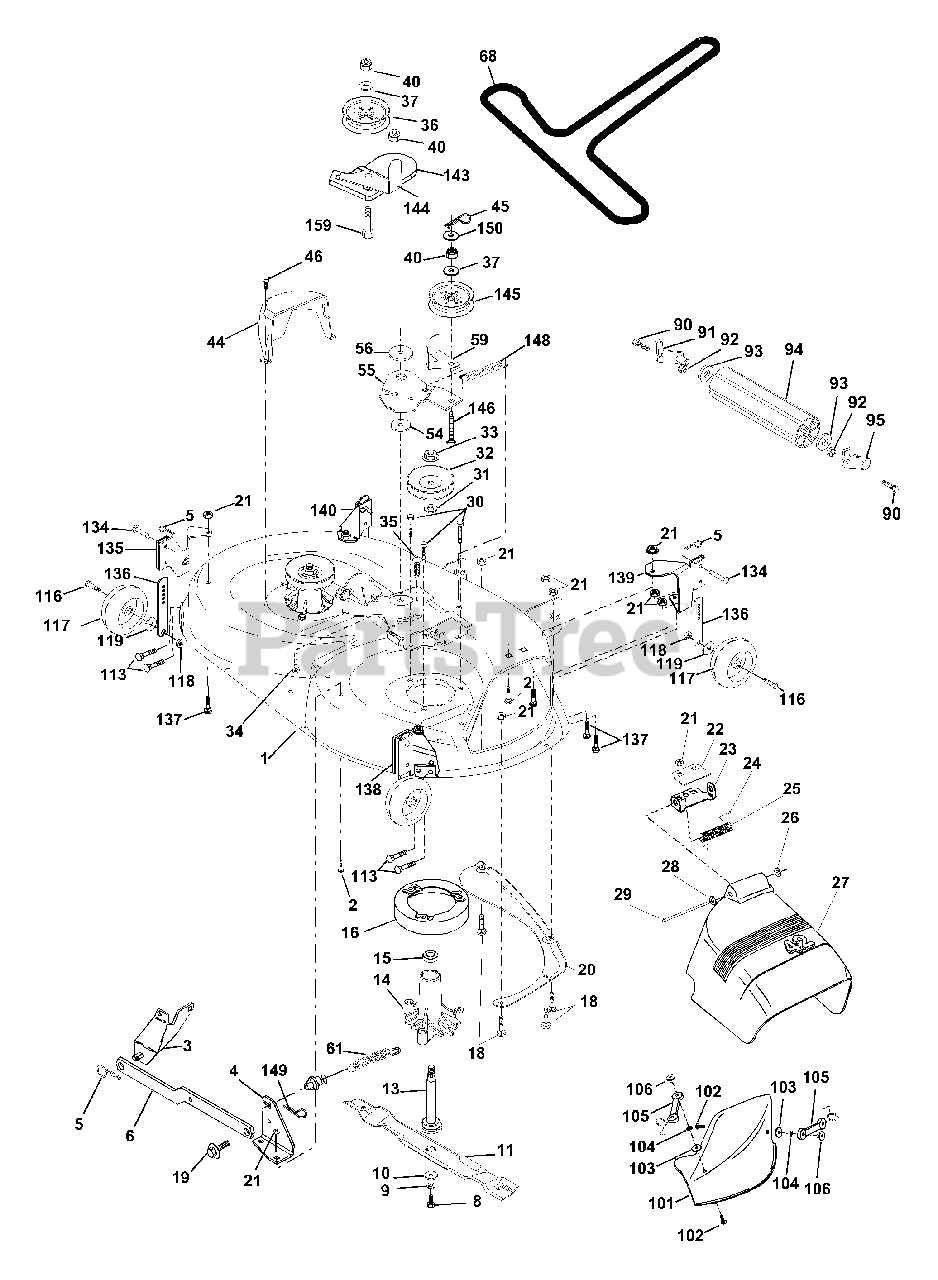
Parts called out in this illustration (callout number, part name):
1	Mower Deck Assembly, 42"
2	Bolt
3	Bracket Assembly,Sway Bar, Front
4	Bracket Sway Bar 38/42" Deck
5	Retainer Spring
6	Arm, Suspension, Rear
8	Bolt, Hex 3/8-24 x 1.25 Gr. 8
9	Washer, Lock
10	Washer,Hardened
11	Blade Mower 42" High Perf.
11	Blade, Mulching
13	Shaft Assembly, Mandrel, Vented
14	Housing, Mandrel, Vented
15	Bearing, Ball, Mandrel
16	Stripper, Mower Deck
18	Bolt, Carriage 5/16-18 x 5/8
19	Bolt, Shoulder
20	Baffle, Vortex
21	Nut Crownlock 5/16-18 UNC
22	Stiffener Bracket
23	Bracket, Deflector
24	Cap, Sleeve
25	Spring, Torsion, Deflector
27	Shield, Deflector
28	Washer 11/32 x 5/8 x 16 Ga.
29	Rod, Hinge
30	Screw Thdrol Washer Head
31	Washer, Spacer
32	Pulley, Mandrel
33	Nut, Toplock, Flanged
35	Fastner, Christmas Tree
36	Pulley, Idler, Flat
37	Washer 13/32 x 13/16 x 16 Gauge
40	Nut Crownlock 3/8-16 UNC
44	Guard, Mandrel, L.H.
45	Retainer
46	Screw, Thd. Roll 1/4-20 x 5/8
54	Washer,Hardened
55	Arm, Idler
56	Spacer, Retainer
59	Guard, TUV Idler
61	Spring Ext Elect Clutch 42" Dck
90	Bolt Fin Hex 3/8-16 Unc x 1
91	Bracket Asm Noseroller Lh
92	Nut Lock Hex w/Ins. 3/8-16 Unc
93	Washer 17/32 x 7/8 x 16 Ga.
94	Roller Nose 38"-50"
95	Bracket Asm Noseroller Rh
101	Mulcher Cover
102	Screw
103	Washer #10
104	Washer, Lock
105	Latch Assembly, Bagger
106	Nut, Weld
113	Screw Tapping 5/16-18 Unc
116	Bolt, Shoulder
117	Wheel, Gauge
118	Nut, Centerlock 3/8-16
119	Washer 3/8 x 7/8 x 14 Gauge
129	Washer 13/32 x 13/16 x 12 Ga
130	Bolt Fin Hex 3/8-16unc x 1 Gr. 5
131	Bolt Rdhd Sqnk 3/8-16unc x 1
134	Pin Head Rivet
135	Bracket Asm Whl GA R LH
136	Bar Adjusting GA WHL
137	Bolt Carr 5/16-18 x 5/8
138	Bracket Asm Whl GA R RH
139	Bracket Asm Whl GA F RH
140	Bracket Asm Whl GA F LH
143	Bracket Arm Idler 42"
144	Keeper Belt 42" Clutch Cable
145	Pulley Idler Flat
146	Bolt Carriage Idler
148	Spring Return Idler
149	Retainer Spring Yellow Zinc
150	Washer 9/32 x 3/4 x 16 Ga.
159	Bolt Rdhd Sqn 3/8-16 UNC x 1- 3/4
